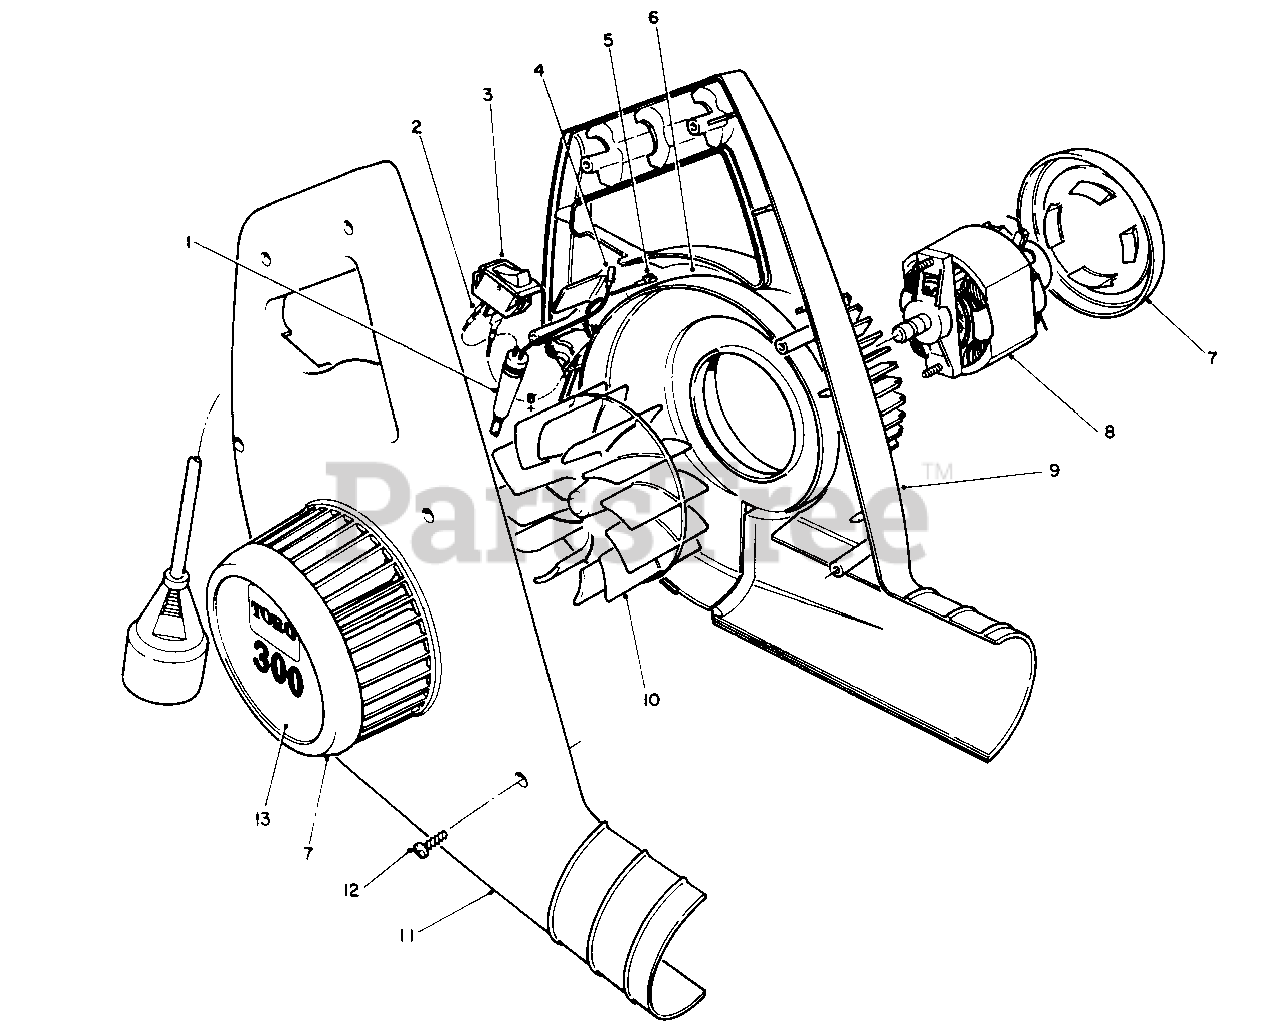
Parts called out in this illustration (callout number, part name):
1	Cord-Power Supply
2	Terminal-Female
4	Coupler-Quick Disconnect
5	Coupler-Female Quick Disconnect
6	Cover-Motor
7	Cover-Intake
8	Motor-120 Volt
9	Housing-L.H.
10	Impeller
11	Housing-R.H.
12	Screw-Thread Forming
13	Decal-300
